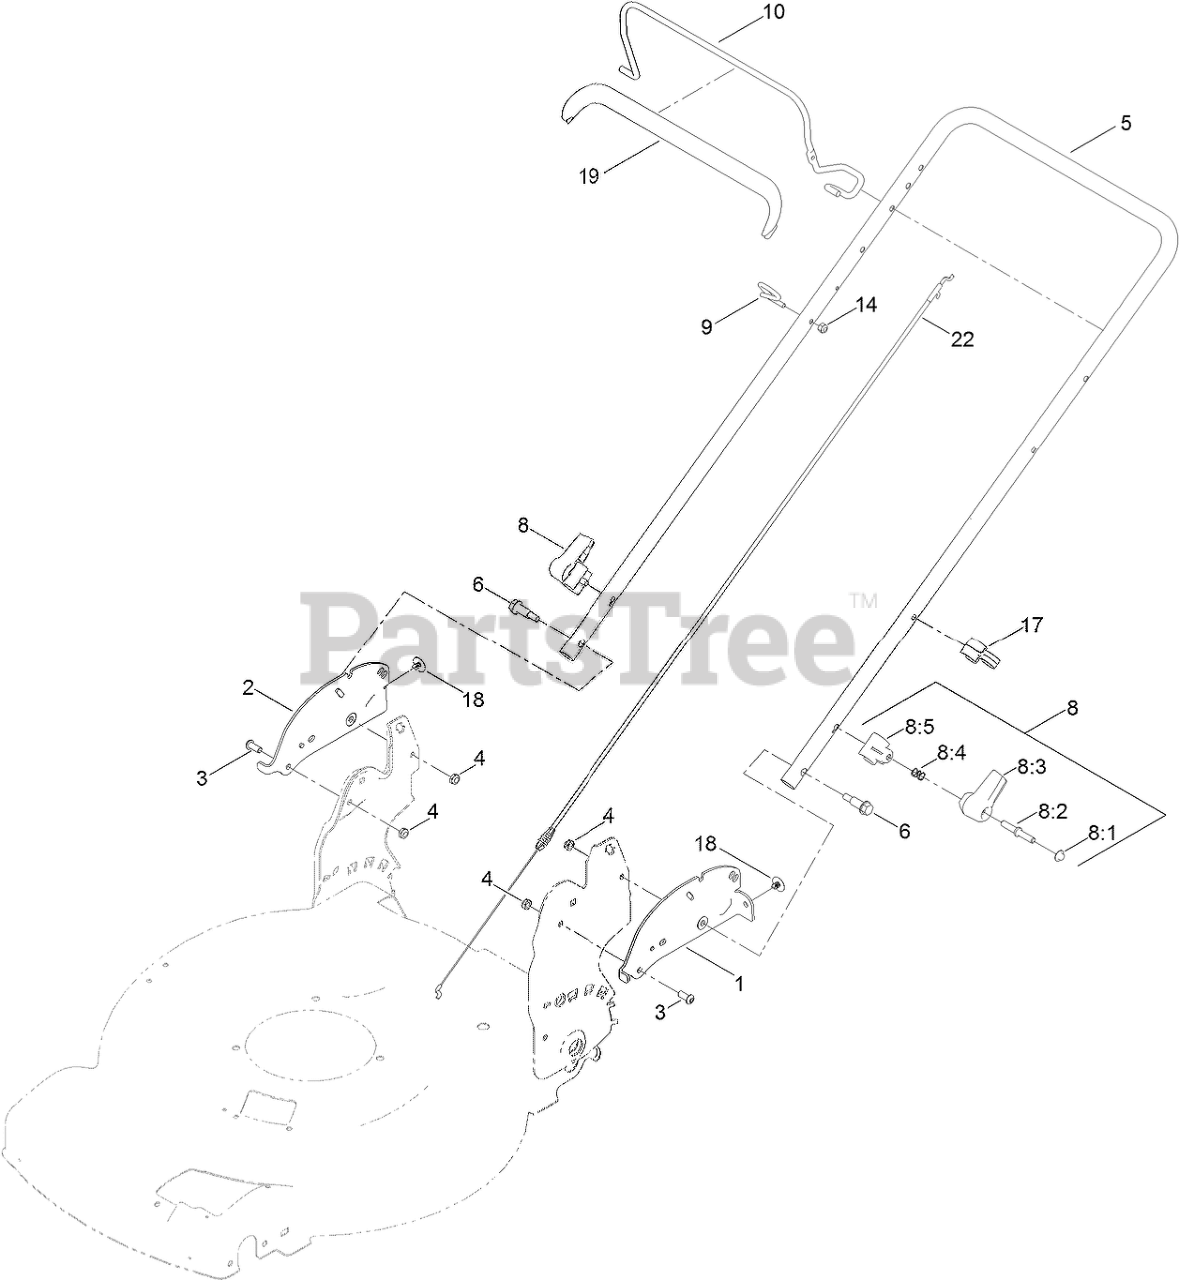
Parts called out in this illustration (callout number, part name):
1	PLATE-HANDLE, LH
2	PLATE-HANDLE, RH
3	SCREW-HSBH
4	NUT-LOCK, NI
6	BOLT-SHOULDER
8	QUICK RELEASE ASM
8:1	NUT-PUSH
8:2	LEVER
8:3	ANCHOR-SPRING
8:4	SPRING-COMPRESSION
8:5	ROD-RELEASE
9	GUIDE-ROPE
10	BAIL-BRAKE
14	NUT-LOCK, NI
17	GUIDE-CABLE
18	CLIP-TREE
19	COVER-BAIL
22	CABLE-BRAKE, ENGINE
